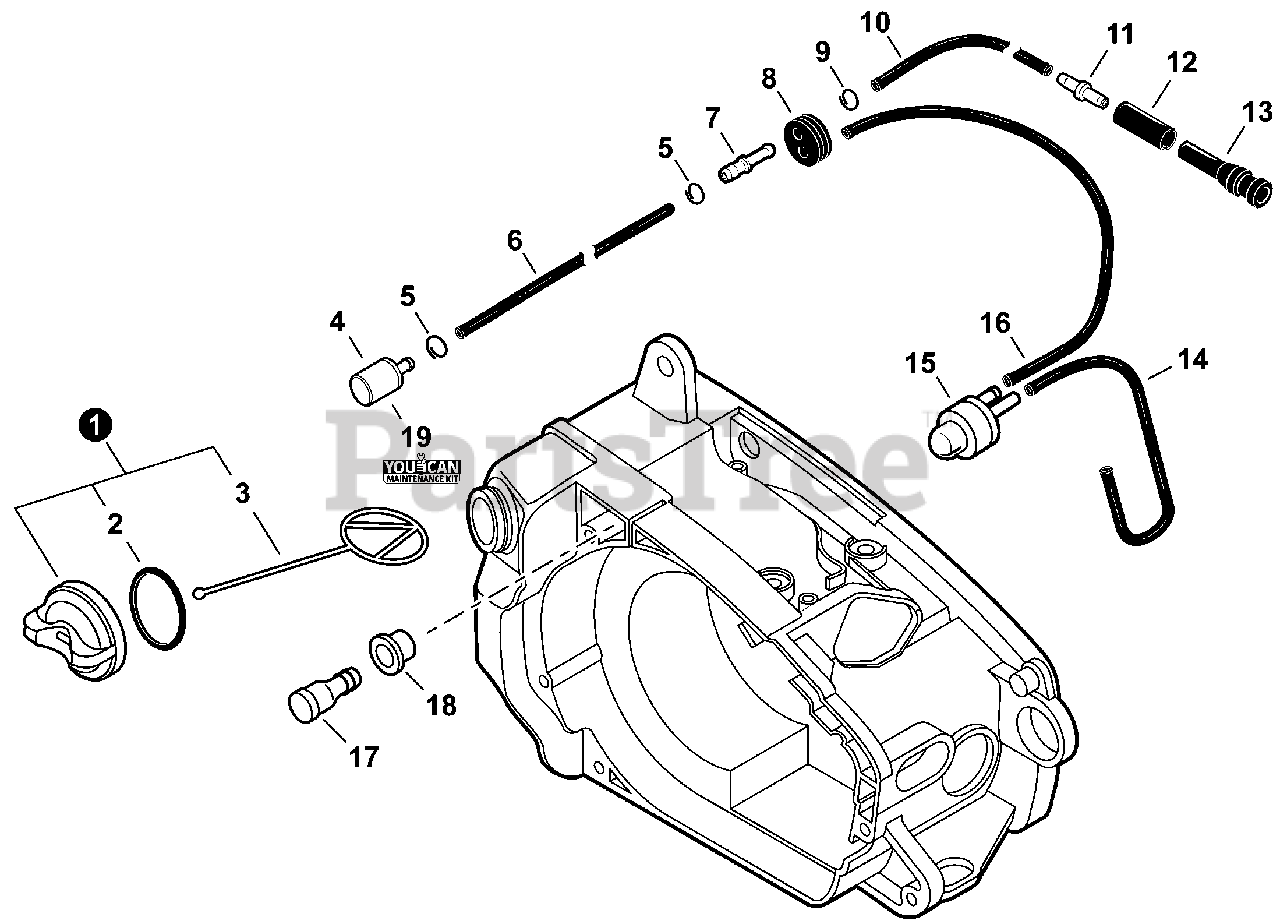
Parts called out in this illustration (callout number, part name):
1	CAP ASSY, FUEL - ORANGE
3	CONNECTOR, CAP L= 60 MM
4	FILTER, FUEL
6	PIPE 3×5×75
7	CONNECTOR, PIPE 5×3.5
8	GROMMET, FUEL
10	PIPE 3×5×145
11	CONNECTOR, PIPE
12	TUBE 6.5×8.5×18
13	PIPE, FUEL 10×6×32
14	PIPE 2.4×5×153
15	BULB, PURGE
16	PIPE 2.4×5×258
17	VENT ASSY
18	GROMMET, FUEL
19	TUNE-UP KIT - YOUCAN™
